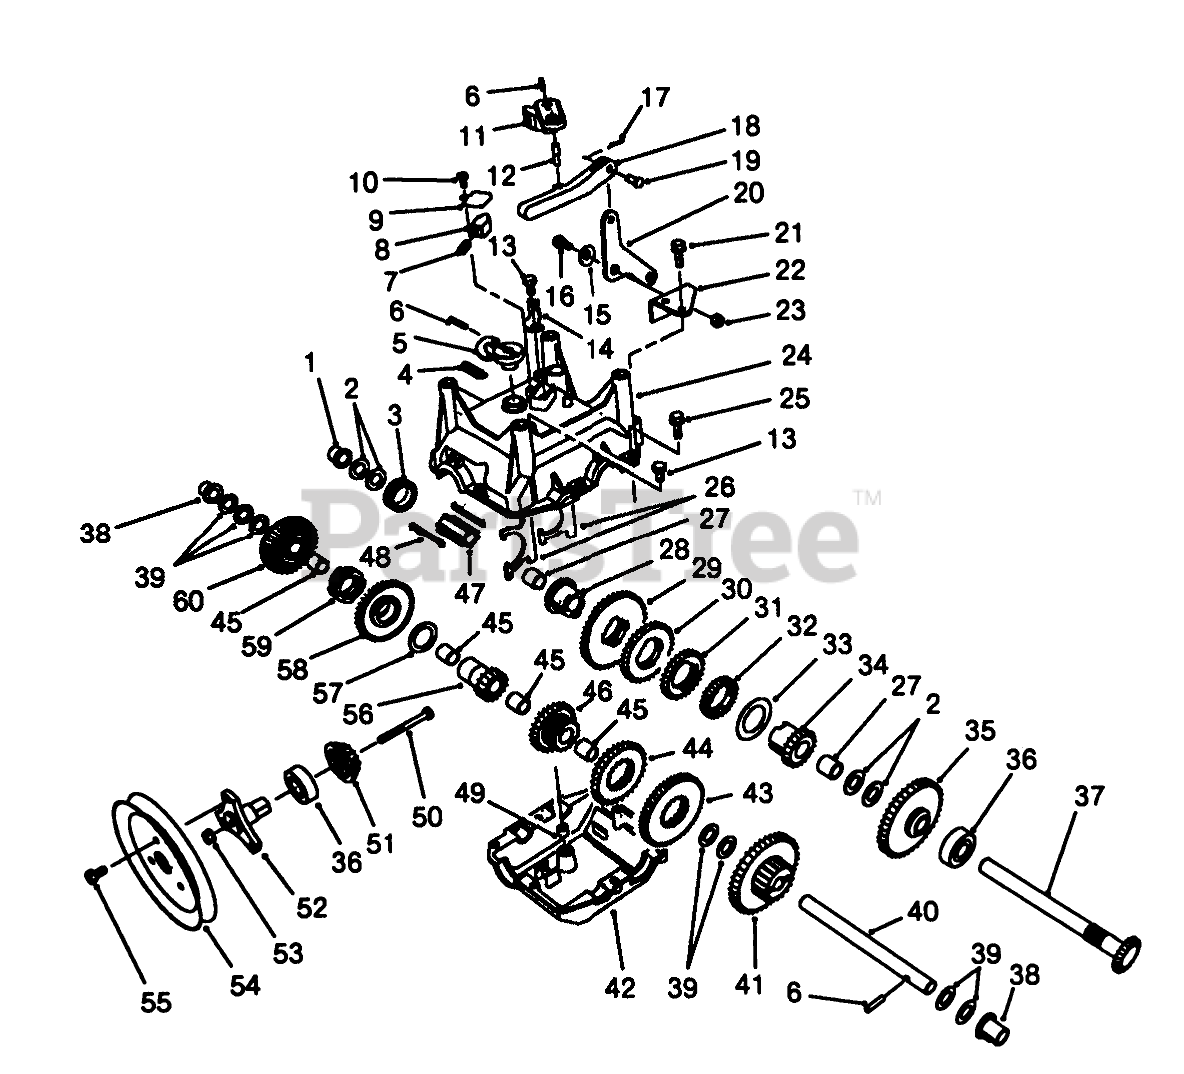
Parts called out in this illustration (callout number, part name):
1	BUSHING-FLANGE, OUTPUT
2	BEARING-THRUST
3	COLLAR-SHIFT
4	SPRING-EXTENSION
5	LEVER
6	PIN-SPRING
7	SPRING-DETENT
8	BUTTON-DETENT
9	COVER-DETENT
10	SCREW-HWH
11	LEVER-SHIFT, GEAR
12	PIN-LINK, GEAR SHIFT
13	SCREW-HWH
14	BRACKET-CABLE
15	WASHER-CURVED
16	SCREW-SHOULDER
17	PIN-COTTER
18	LINK-SHIFT, GEAR
19	PIN-CLEVIS
20	BELLCRANK
21	SCREW-HWH
22	BRACKET-BELLCRANK
23	NUT-LOCK, NI
24	GEARCASE-UPPER, CASING
26	YOKE-SHIFT
27	BUSHING-OUTPUT
28	SLEEVE-GEAR
29	GEAR-45 T
30	GEAR-34 T
31	GEAR-27 T
32	GEAR-29 T
33	WASHER-THRUST
34	GEAR-SLEEVE, 19 T
35	GEAR-41 T
36	BEARING-BALL
37	SHAFT-OUTPUT
38	BUSHING-INTERMEDIATE
39	WASHER-THRUST
40	SHAFT-INTERMEDIATE
41	GEAR-19/41 T
42	GEARCASE-LOWER, CASING
43	GEAR-51 T
44	GEAR-33 T
45	Bushing-Output
46	Gear-26T
47	Sleeve-Shift
48	KEY-SHIFT
49	BUSHING-YOKE
50	SCREW-HH
51	PINION-BEVEL
52	HUB-PULLEY
53	NUT-HHF
54	TRACTION-SHEAVE, HALF
55	SCREW
56	GEAR-BEVEL, 15 T
57	WASHER-THRUST
58	Gear-Bevel 36T
59	Collar-Shift
60	Gear-Bevel Reverse 36T
